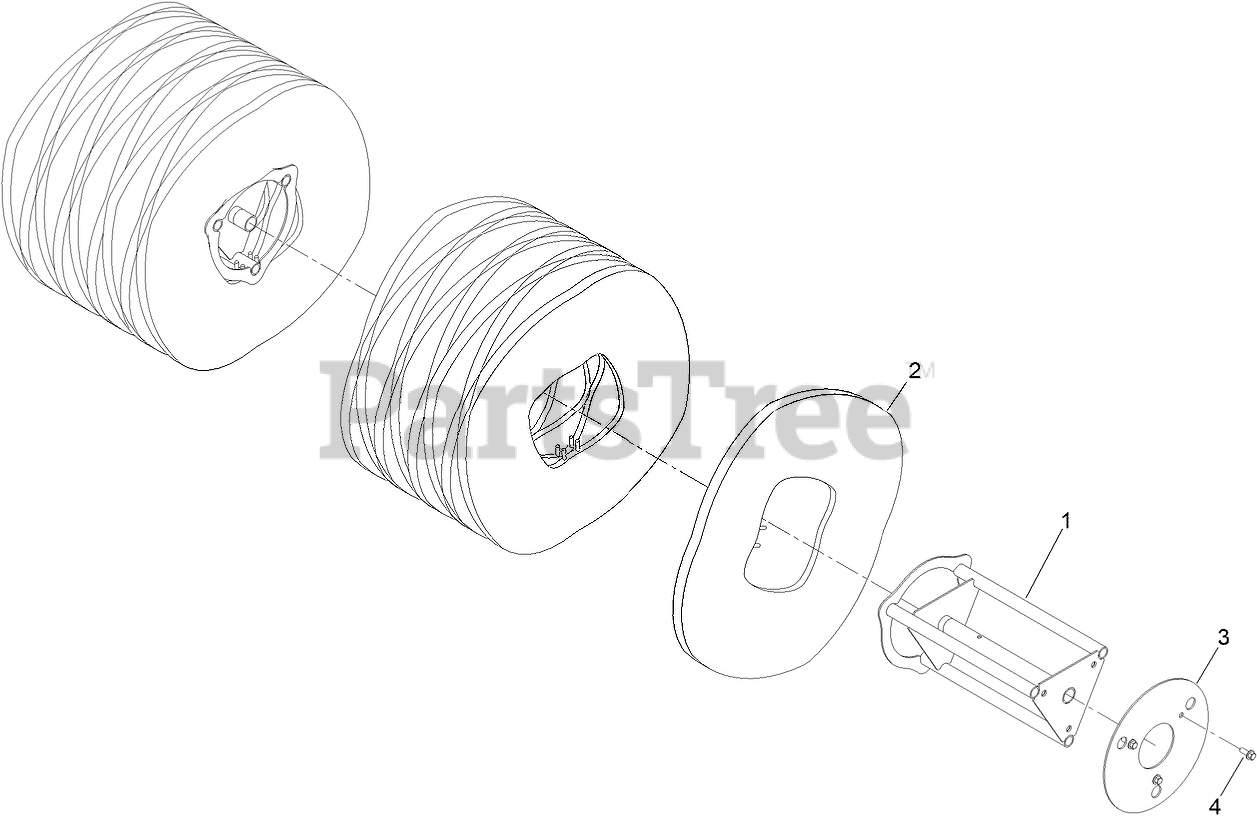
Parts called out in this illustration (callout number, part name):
1	CORE-BROOM
2	SEGMENT-POLY
3	PLATE-END, RETAINER
4	SCREW-HHF
